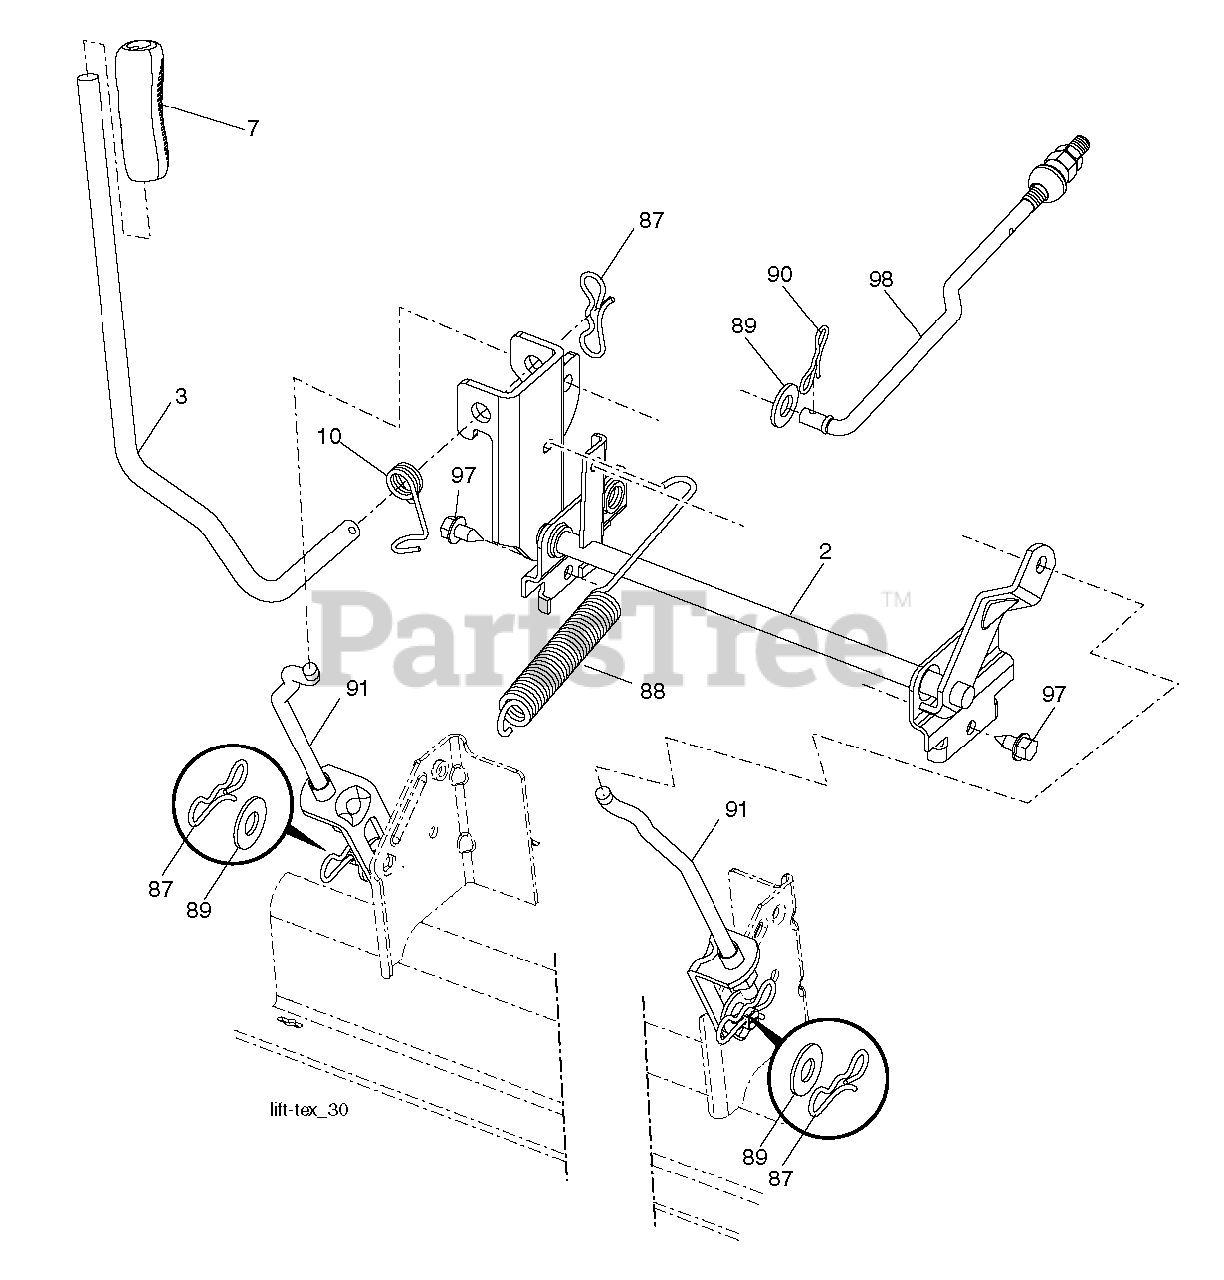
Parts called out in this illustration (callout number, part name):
2	SHAFT.ASM.CROSS.LIFT
3	LEVER.LIFT.HANDLE.LT
7	GRIP.HANDLE.LIFT.PVC.BLACK
10	SPRING.TORSION.LIFT.HANDLE
87	PIN.COTTER.7/16.BOW TI.
88	SPRING.LIFT.ASSIST
89	WASHER.CLEAR.ZINC
90	PIN.COTTER.5/16.BOW TI
91	LINK.LIFT.ASM.REAR.GT.
97	SCREW, 3/8-16X3/4
98	Poulan TBD
